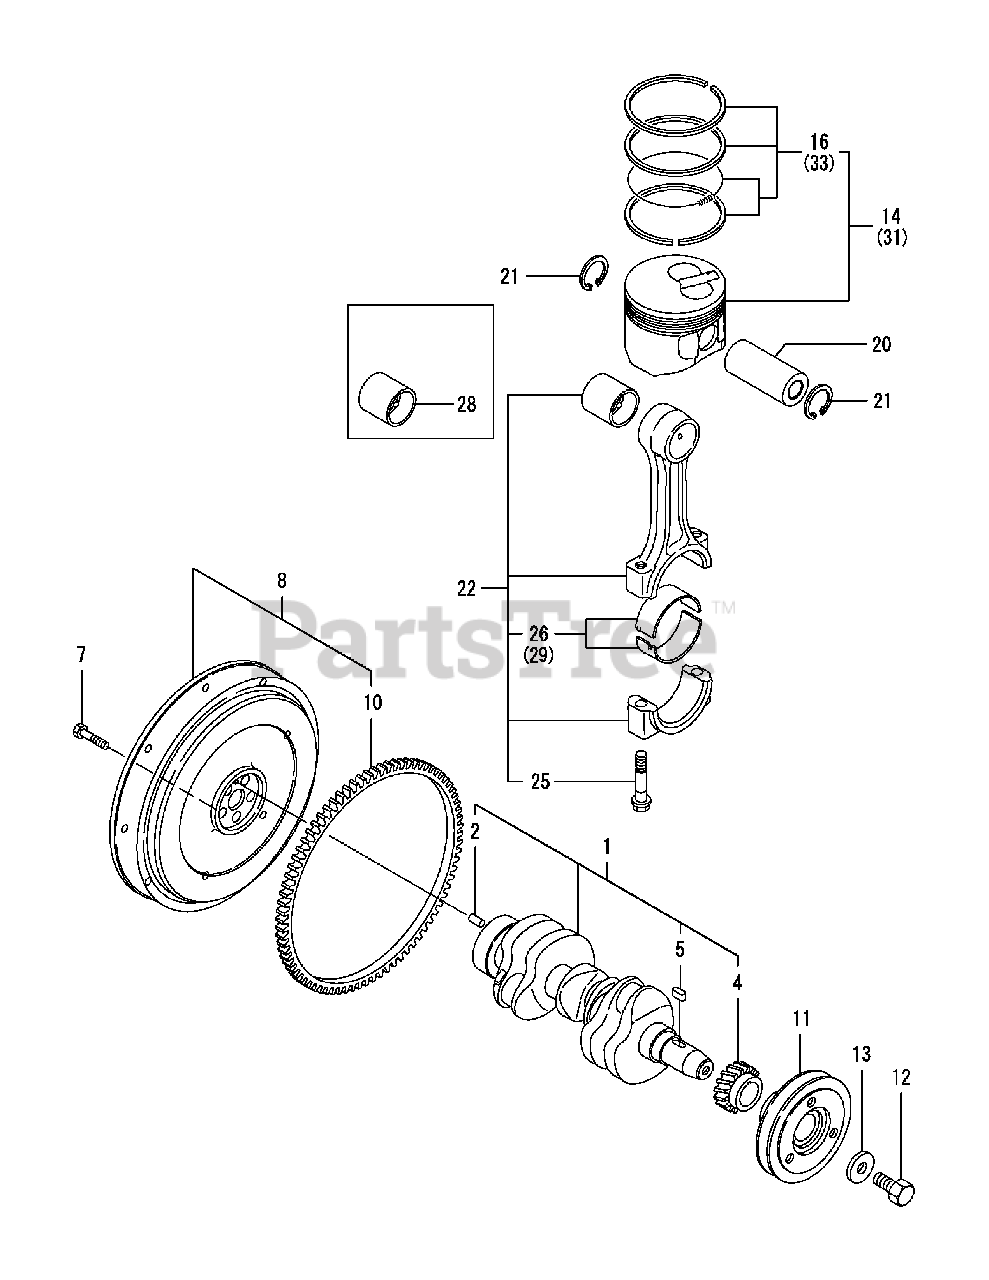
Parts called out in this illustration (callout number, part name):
1	Crankshaft Assembly
2	Parallel Pin 8 x 16
4	Gear, Crankshaft
7	Bolt, Flywheel
8	Flywheel Assembly
11	V-Pulley, Crankshaft
12	Bolt M12 x 1.25, Flange
14	Piston Assembly
22	Rod Assembly, Connecting
25	Bolt, Connecting Rod
26	Metal Assembly, Crank Pin
28	Bush, Piston Pin
31	Piston Assembly
